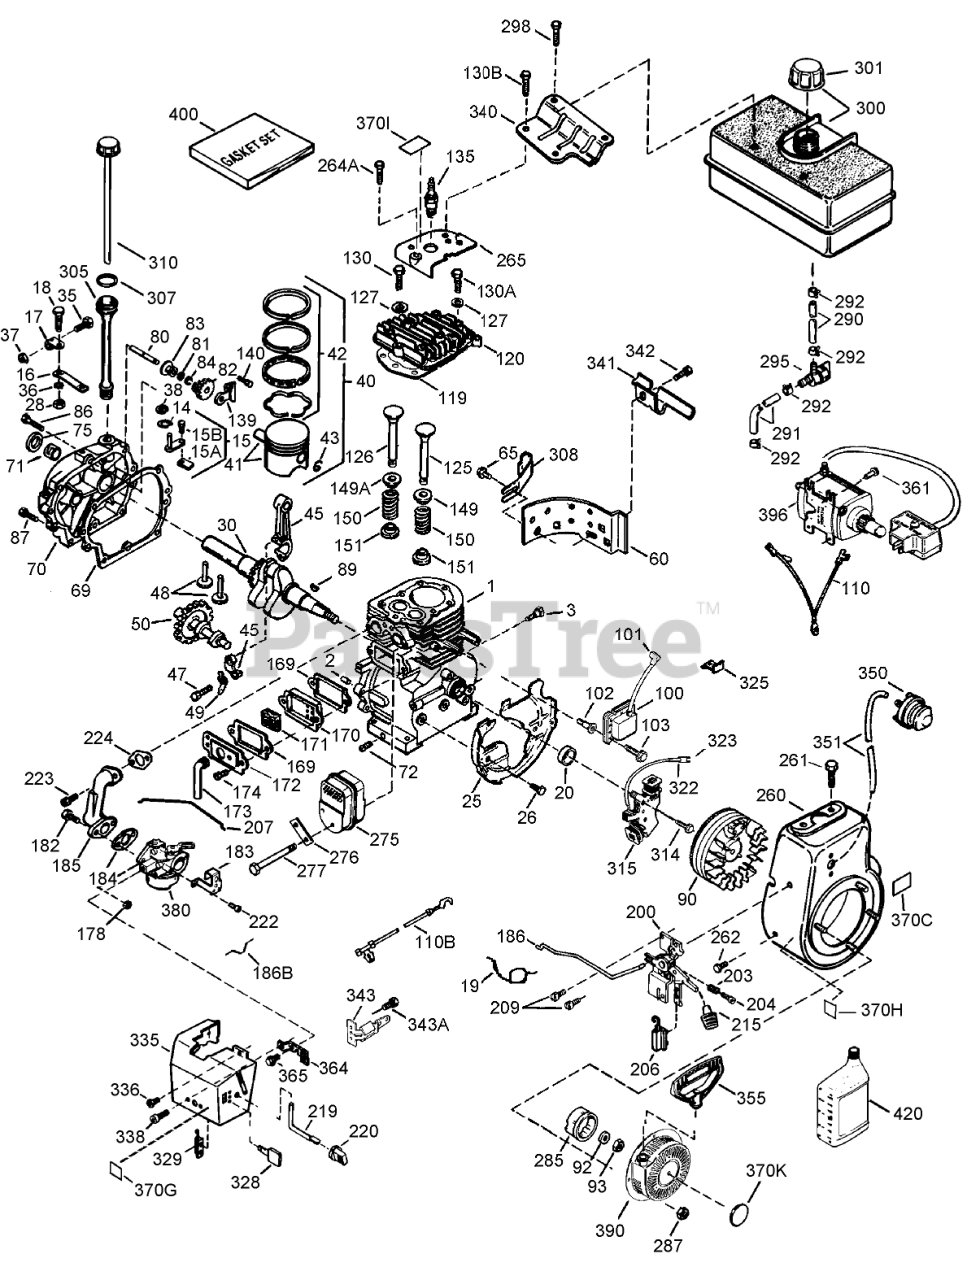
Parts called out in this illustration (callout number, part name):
182	Screw (1/4-28x1)
183	Bracket-Choke
184	Gasket-Carburetor To Intake Pipe
185	Pipe-Intake
186	Link-Governor
186B	Spring-Choke
200	Bracket-Control (Includes 19, 203, 204, 206)
203	Spring-Compression
204	Screw (T-10, 5-40x7/16)
206	Terminal
207	Link-Throttle
209	Screw (10-32 x 1/2)
215	Knob-Control
219	Rod-Choke
220	Knob-Control
222	Screw (10-32 x 1/2)
223	Screw (T-30, 5/16-18x1-3/32)
224	Gasket-Pipe, Intake
260	Housing-Blower
261	Screw (5/16-18x3/4)
262	Screw (5/16-18x9/16)
264A	Screw (1/2-20x5/8)
265	Cover-Head, Cylinder (Black)
275	Muffler
276	Plate-Locking
277	Screw (5/16-18x4-3/16)
285	Cup-Starter
287	Nut and Lock Washer (1/4-28)
290	Line-Fuel (8.62)
291	Line-Fuel
292	Clamp-Line, Fuel
295	Valve-Shut Off, Fuel (Includes 292)
298	Screw (1/4-15x7/8)
300	Tank-Fuel (Includes 292, 301)
301	Cap-Fuel (Black) (1-1/2 I D)
305	Tube-Fill, Oil
307	O-Ring
308	Clip-Tube, Fill
310	Dipstick
314	Screw (1/4-20 x 3/4)
315	Coil-Alternator, 18 Watt (Includes 322, 323)
322	Body-Connector
323	Terminal
325	Clip-Wire
328	Key-Ignition
329	Terminal
335	Cover-Carburetor (Black)
336	Screw (10-32x1/2)
338	Screw (10-32 x 3/8)
340	Bracket-Tank, Fuel (Black)
341	Bracket-Tank, Fuel
342	Screw (1/4-20x19/32)
343	Bracket-Switch, Key (Includes 343A)
343A	Screw (8-32 x 23/64)
350	Primer ASM
351	Line-Primer (12 inches)
355	Handle-Starter, Mitten Grip
361	Screw (T-30, 1/4-20x15/32)
364	Bracket-Cover, Carburetor
365	Screw (8-32x27/64)
370C	Decal-Primer, International Symbol
370G	Decal-Instruction
370H	Decal-Speed Control and Choke
370I	Decal-Warning (Bilingual)
370K	Decal-Tecumseh Logo for Top of Recoil Starter
380	Carburetor ASM (Includes 184)
390	Starter-Rewind (Note: This engine could have been built with Starter 590733)
396	Starter-Electric (110 Volt)
400	Gasket Set (Includes 69, 119, 169, 184, 224)
420	Oil-Engine, S A E 5W30
